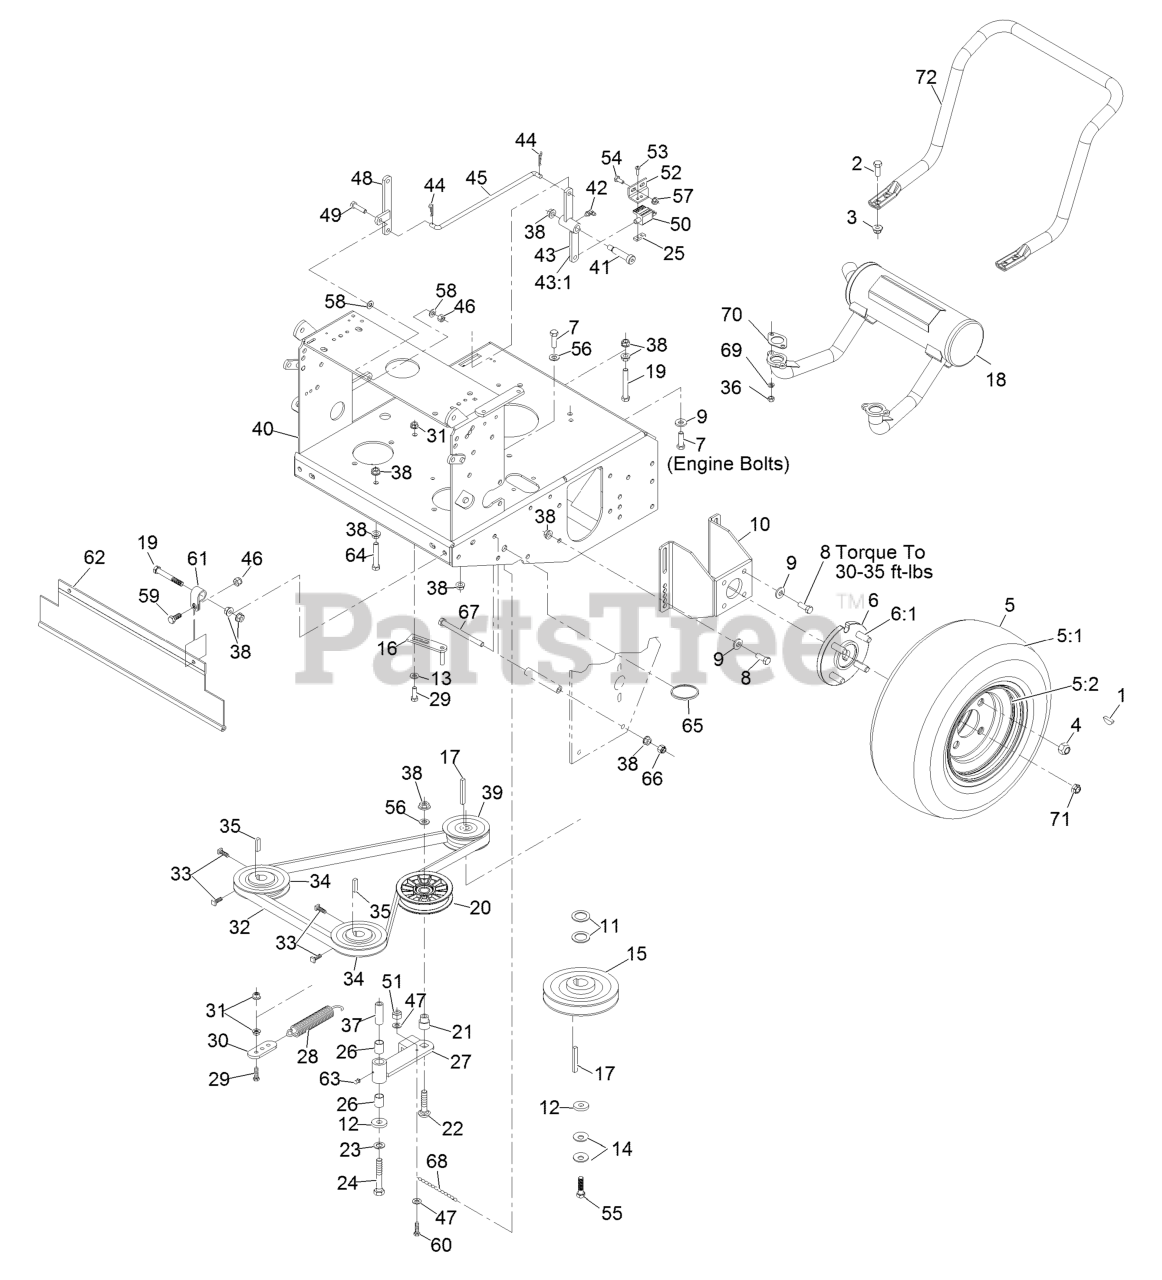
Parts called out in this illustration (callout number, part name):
1	KEY-WOODRUFF
2	SCREW-HH
3	NUT-HF, NI
4	NUT-LUG
5	WHEEL AND TIRE ASM
5:1	TIRE-TURFMASTER
5:2	RIM-WHEEL
6	WHEEL HUB ASM
6:1	STUD-WHEEL
7	SCREW-HH
8	SCREW-HH
9	WASHER-BELLEVILLE
10	MOUNT-MOTOR
11	WASHER-SPACER
13	WASHER-SPRING
14	WASHER-SPRING
16	GUIDE-BELT
18	MUFFLER-HORIZONTAL
19	SCREW-HH
20	PULLEY-IDLER, FLAT
21	BUSHING-IDLER
22	SCREW-CARR
23	WASHER-LOCK
24	BOLT-CARR
25	PLATE-TAPPED
26	SLEEVE-BEARING
27	IDLER ARM ASM
28	SPRING-EXTENSION
29	SCREW-HH
30	ANCHOR-SPRING
32	BELT-COG
33	SCREW-SET, SQH
34	SHEAVE ASM
37	BUSHING
38	NUT-HHF, WHIZ
39	PULLEY
40	ASM, VH ENGINE DECK W/DEC
42	FITTING-GREASE, 90 DEG
43	BELLCRANK ASM
44	PIN-COTTER
45	LINKAGE-ENGAGE, BLADE
46	NUT-LOCK, NI
47	WASHER-FLAT
48	BELLCRANK
49	SCREW-HH
50	SWITCH-OPEN, NORMALLY
51	NUT-LOCK, NI
52	BRACKET-SWITCH, BLADE
53	SCREW-PPH
54	SCREW-HH
55	SCREW-HH
56	WASHER-FLAT
58	WASHER-PLAIN
59	SCREW-HH
60	SCREW-HSH
61	CLIP-LOOM
62	SHIELD-DRAG
63	FITTING-GREASE
64	SCREW-HH
65	RING-SPLIT
66	NUT-LOCK, NI
67	SCREW-HH
68	CHAIN-LINK, TWIST
69	WASHER-LOCK
70	GASKET-EXHAUST
71	NUT-LOCK
72	GUARD-MUFFLER
